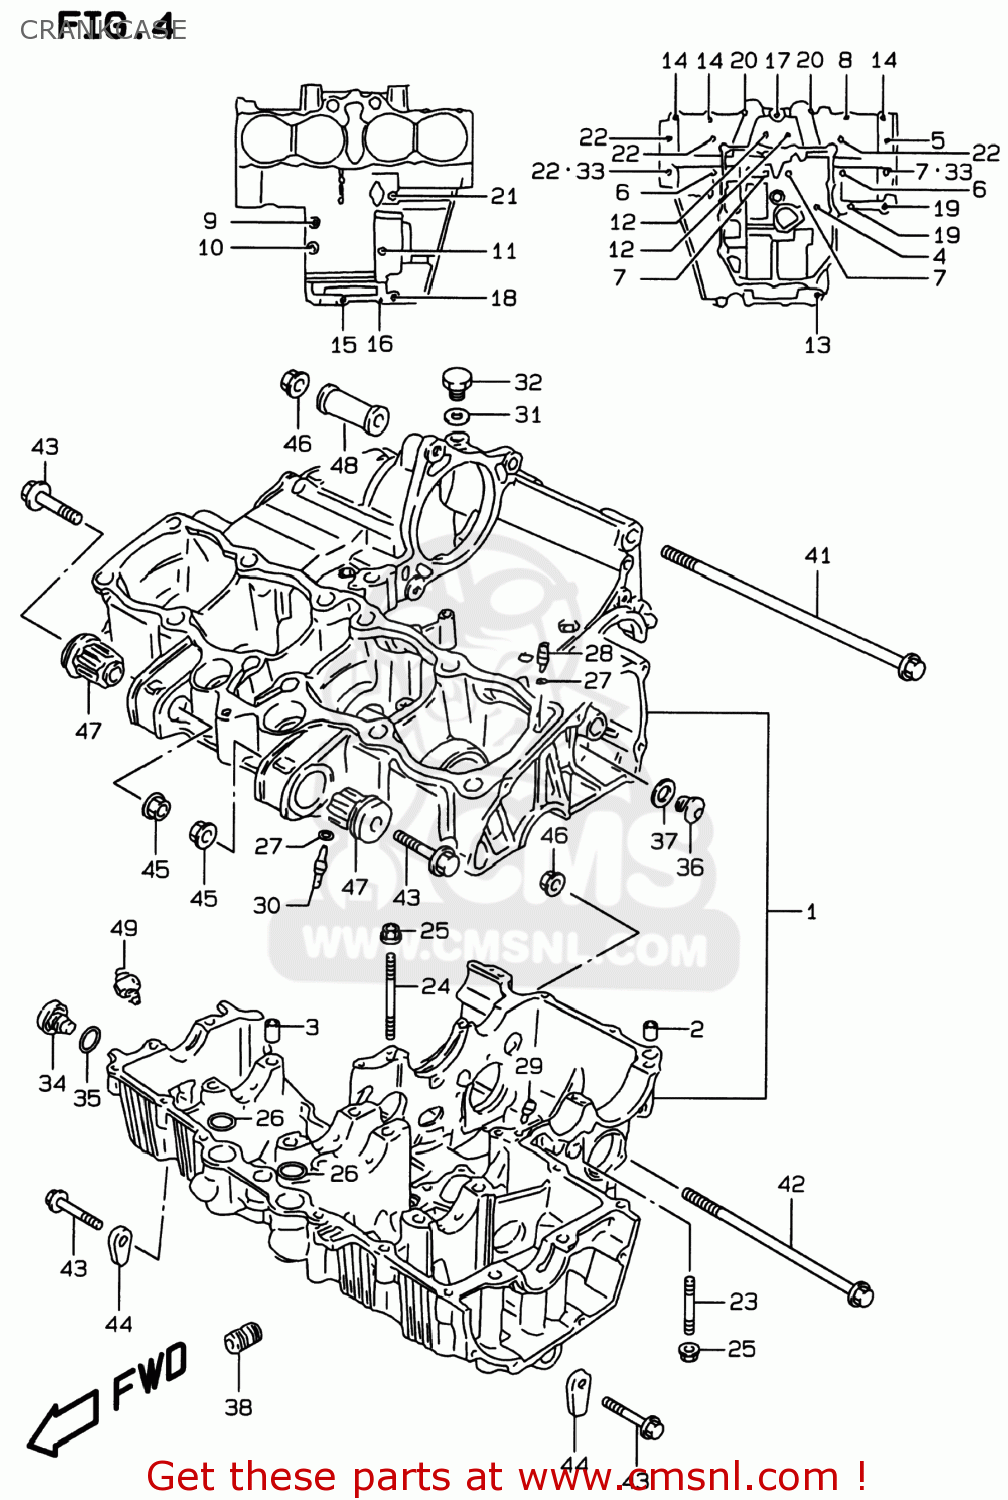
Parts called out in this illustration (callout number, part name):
1	CRANKCASE SET
2	PIN(10.4X13X22)
3	PIN(8.4X11X20)
4	BOLT(6X105)
5	BOLT(8X105)
6	BOLT(8X125)
7	BOLT(8X115)
8	BOLT
9	BOLT
10	BOLT,CL.COVER
11	BOLT
12	BOLT
13	BOLT
14	BOLT
15	BOLT
16	BOLT
17	BOLT
18	BOLT
19	BOLT, HYDRAULIC UNIT NO.2
20	BOLT
21	BOLT
22	BOLT(8X95)
23	STUD BOLT
24	STUD BOLT
25	NUT
26	O RING(D:2.5,ID:21)
27	O RING(D:1.2,ID:4)
28	JET,AIR
29	JET
30	JET,OIL GALLERY
31	GASKET(12.1X16.2X3.7) (NAS)
32	PLUG(12X9)
33	GASKET(8.5X17X2.3) (NAS)
34	PLUG
35	O RING(D:2.4,ID:16.8)
36	PLUG
37	GASKET(13.8X18.8X4.8) (NAS)
38	UNION,OIL STAND
39	PLATE,CRANK THRUST
40	PLATE,CRANK THRUST
41	BOLT(10X180)
42	BOLT(10X130)
43	BOLT
44	NUT
45	NUT
46	NUT
47	BUSH,ENGINE MOUNTING
48	SPACER,ENGINE MOUNT(L27)
49	SWITCH ASSEMBLY,OIL PRESSURE
